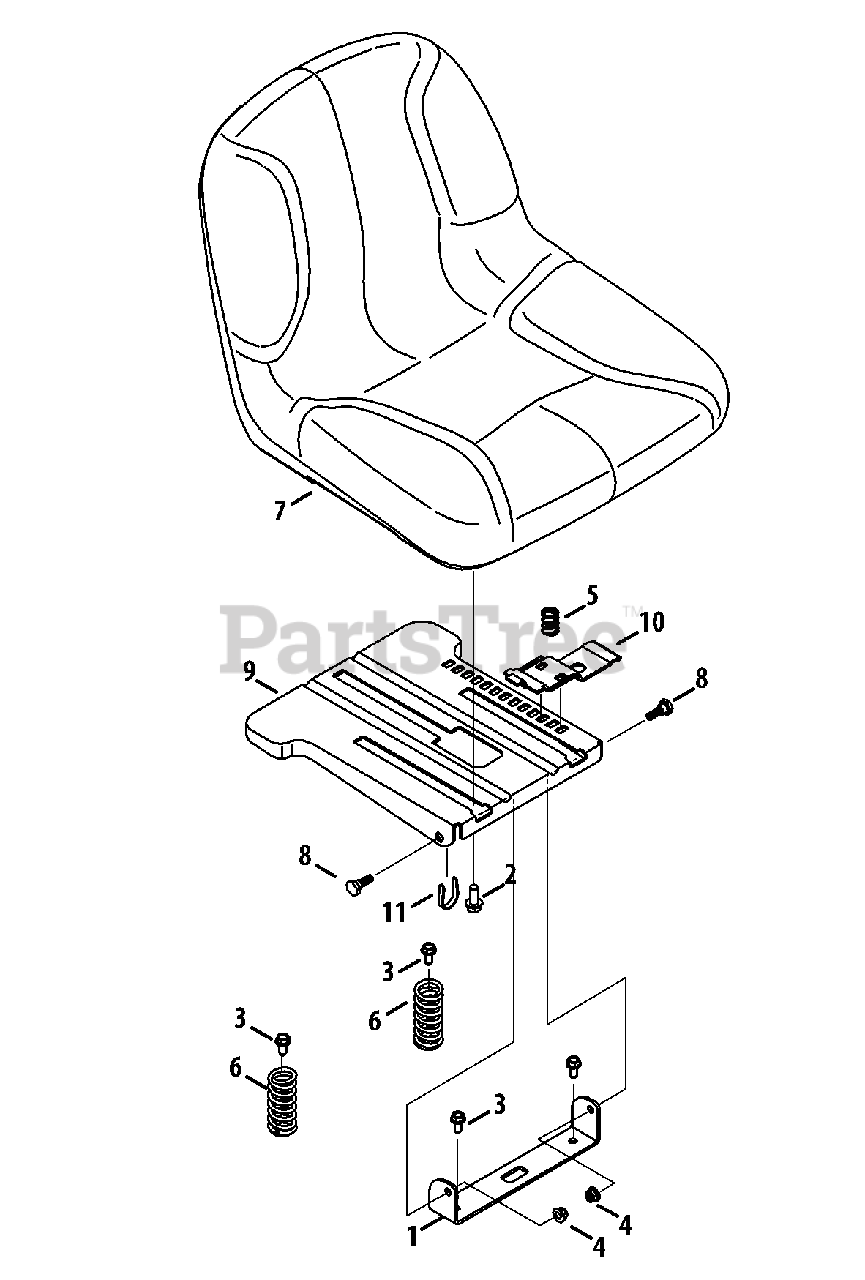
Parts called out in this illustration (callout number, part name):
1	Seat Bracket
2	Hex Flange Bolt, 3/8-16 x .875
3	Hex Washer Screw, 5/16-18 x .750
4	Flange Lock Nut, 5/16-18
5	Compression Spring, .68 x 1.065 x .055
6	Compression Spring, 1.50 x 3.90 x .200
7	Seat
8	Shoulder Screw, 5/16-18 x .437 x .268
9	Seat Mount Bracket
10	Seat Adjustment Lever
